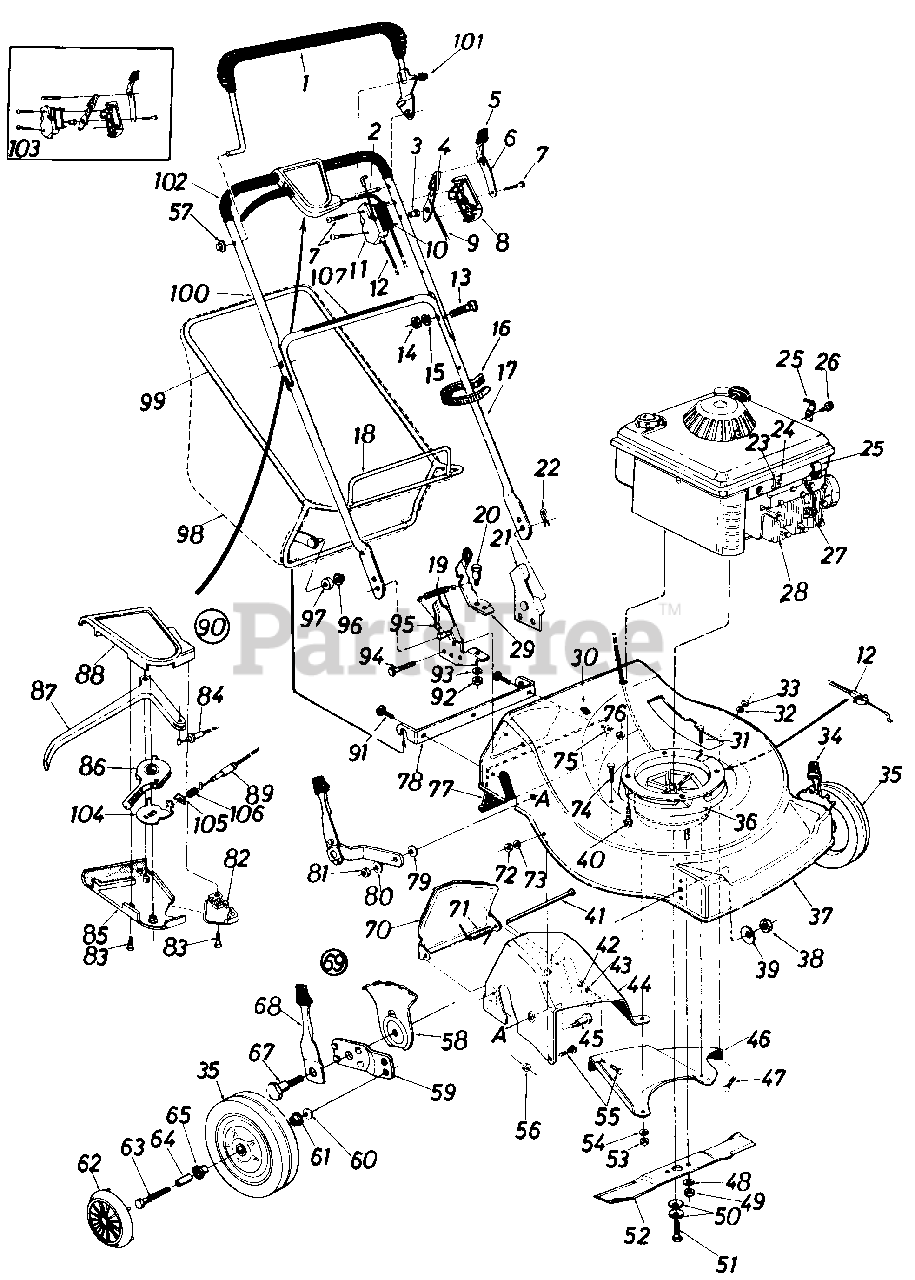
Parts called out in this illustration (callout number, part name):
1	L.H. Bail Ass'y.
3	Control Disc Pin
4	Throttle Control Lever
5	Spring Lever Knob
6	Lockout Spring
7	Truss Mach. Hi-B Tap Scr. #12 x 1.50" Lg.
8	Control Panel Half
9	Throttle Control Wire
10	Control Label
11	Clutch Panel Half
12	Clutch Cable 46" Lg.
13	Carr. Bolt 5/16-18 x 1.38"
14	Hex Nut 5/16-18 Thd.
15	L-Wash. 5116" I.D.
16	Cable Tie
17	Lower Handle
20	Shld. Bolt .437" Dia. x .162
21	Handle Brkt. Ass'y. L.H.
22	Hairpin Cotter 5/16" Dia.
23	Hex B-Tap Scr. #10 x .621'
24	Casing Clamp
25	Cable Clip
26	Hex B-Tap Scr. #10 x .38"
27	Spark Plug Insulator
28	Engine
29	Catcher Lock Lever w/Knob
31	Hex TT-Tap Scr. 1/4-20 X .75" Lg.
32	L-Wash. 1/4" I.D.
33	Hex Nut 1/4-20 Thd.
34	Height Adj. Ass'y. L.H.
35	Front Wheel Ass'y. Comp.
36	Blade/Brake Clutch Ass'y. Comp.
39	Bell-Wash. .39" I.D. x 1.13
40	Hex Wash. Hd. TT-Tap Scr. 3/8-16 x 1.0" Lg.
42	Hex Nut 1/4-20 Thd.
43	L-Wash. 1/4" I.D.
44	Rear Chute R.H.
45	Shld. Bolt.500" Dia.
46	Rear Baffle L.H.
47	Carr. Bolt 1/4-20 x .50" Lg.
48	L-Wash. 318" I.D.
49	Hex Nut 3/8-24 Thd. Gr. 8
50	Bell-Wash. .40" I.D. x .88"
51	Hex Cl-Bolt 3/8-24 x 2.0" Lg. (Grade 8)
53	Hex Nut 1/4-20 Thd.
54	L-Wash. 1/4" I.D.*
55	Carr. Bolt 1/4-20 X .50" Lg.
56	Hex Sems Nut 1/4-20 Thd.
58	Height Adj. Plate
59	Wheel Pivot Bar
60	Bell-Wash. .40'1 I.D. x .88
61	Bearing 3/8" I.D.
62	Plastic Hub Cap
65	Bearing 1/2" I.D.
67	Shld. Bolt .50" Dia. x .430
68	Spring Lever Ass'y. w/Knob
69	Height Adj. Ass'y. R.H.
70	Chute Door
71	Torsion Spring
72	Hex Nut 1/4-20 Thd.
73	L-Wash. 1/4" I.D.
74	Hex Bolt 1/4-20 x .88n Lg.
75	Fl-Wash. .285" I.D. x 1.25"
76	Hex Sems Nut 1/4-20 Thd.
78	Grass Catcher Hitch Brkt.
79	Bell-Wash. .40n l.D. x 1.13n
80	Bell-Wash. .40n l.D. x .881'
81	Hex Jam Nut 3/8-16 Thd.
82	Cable Mounting Cap
83	Flat "C"-Sunk Hd. Tap Scr. #10 x .75n Lg.
84	S.P. Cable 53" Lg.
85	3-Sp. S.P. Control Lower Cover
86	Shimano 3-Sp. Shift Lever
87	Control Lever
88	3-Sp. S.P. Control Upper Cover
89	Shimano 3-Sp. Solid Shift Cable
90	Clutch Control Hsg. Comp.
91	Carr. Bolt 1/4-20 x .75n Lg.
92	Hex Nut 5/16-18 Thd.
93	L-Wash. 5/16" I.D.
94	Hex L-Wash. Hd. AB-Tap Scr. 1/4" x.62" Lg.
95	Handle Brkt. Ass'y. R.H.
96	Push Nut 3/8n Rod
97	Plastic Roller
98	Grass Bag (w/o Flip Top)
99	Catcher Upper Frame
100	Upper Handle
102	Grip
103	Control Housing Comp.
104	Shimano 3-Sp. Shift Lever Brkt.
105	Shimano 3-Sp. Cable Spring Brkt.
106	Shimano 3-Sp. Cable Mounting Spring
107	Instruction Label
8365-000-7	Hardware Pack
